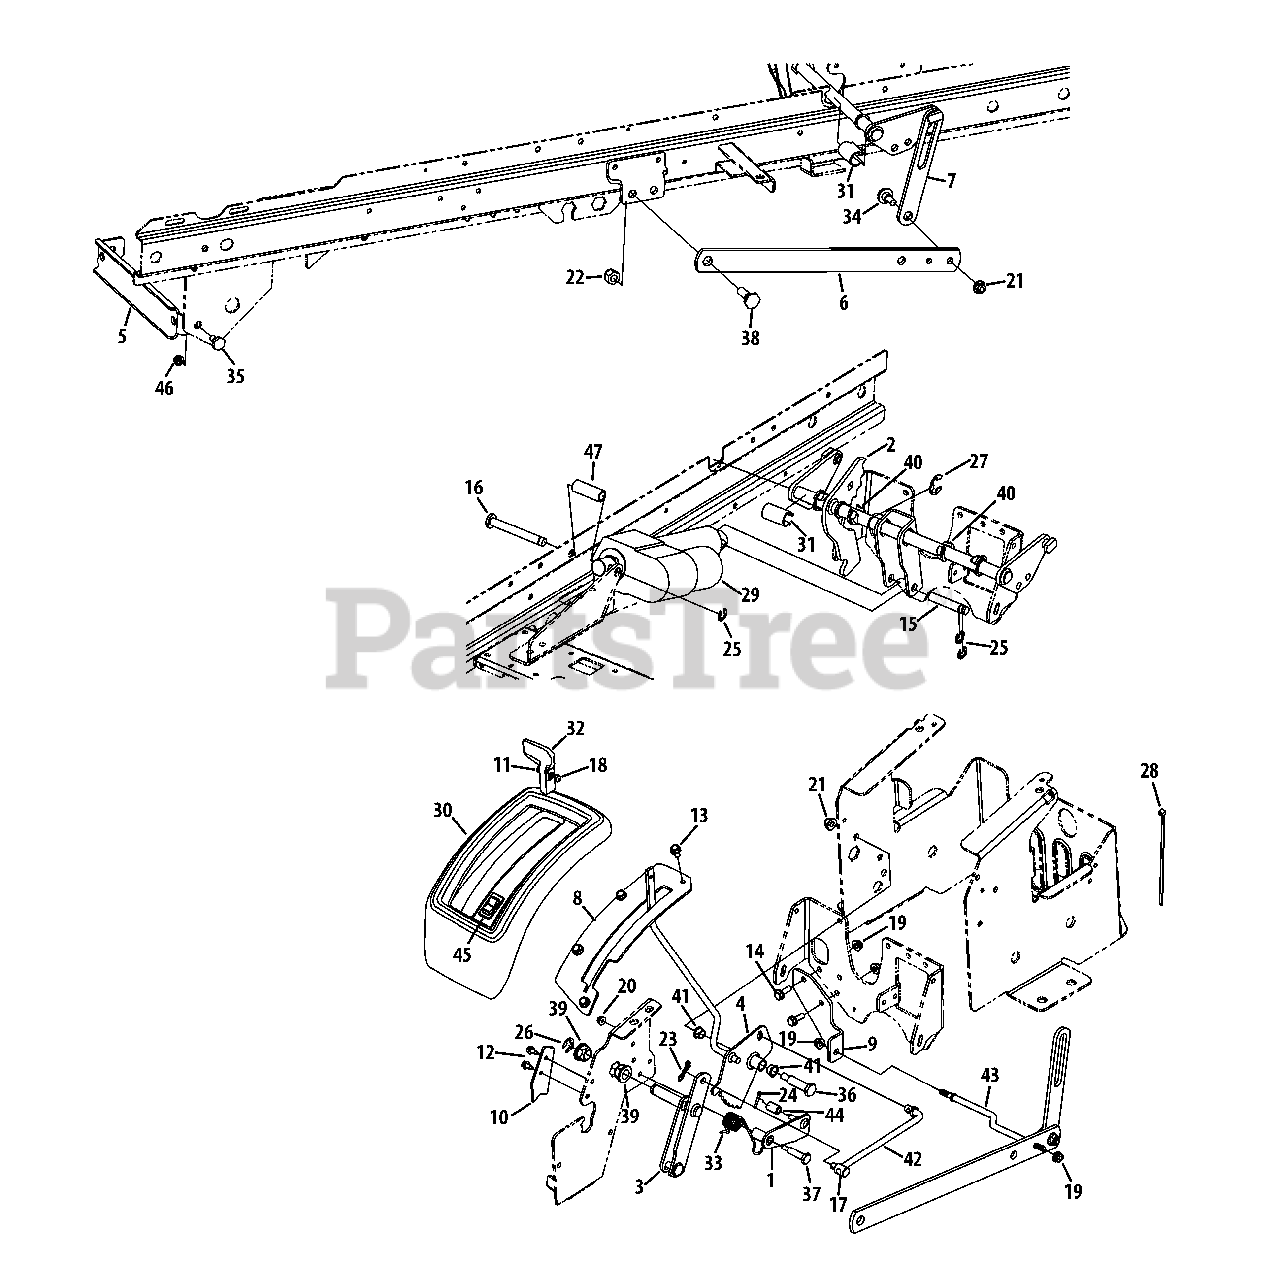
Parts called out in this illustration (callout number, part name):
1	Hub Lift Assembly
2	Electric Shift Assembly
3	Deck Height Adjustment Weldment
4	Lift Lever Bracket Assembly
5	Front Hanger Bracket
7	Lift Link Plate
9	Sway Bar Mount Bracket
10	Bearing Stop Plate
11	Machine Screw, #10-24 x .625
12	Hex Washer Screw, 1/4-20 x .500
13	Hex Washer Screw, 5/16-18 x .625
14	Hex Washer Screw, 5/16-18 x .875
15	PIN, .50 x 3.5
16	Clevis Pin, .50 x 4.0
17	Ferrule, 3/8-24 x .375
18	Hex Lock Nut, #10-24
19	Flange Lock Nut, 5/16-18
20	Flange Lock Nut, 1/4-20
21	Flange Lock Nut, 3/8-16
22	Hex Lock Nut, 1/2-13
23	Bow-Tie Cotter Pin, 72
24	Cotter Pin, .125 x .75
25	E-Ring, .500
26	E-Ring, .625
27	E-Ring, .875
28	Cable Tie, 3/16 x .05 x 7.4
29	Plow Lift Actuator
30	Lift Cover
32	Electric Lift Knob
33	Torsion Spring
34	Shoulder Screw, 3/8-16 x .562 x .360
35	Shoulder Screw, 1/2 x .29
36	Shoulder Screw, .498 x 1.635
37	Shoulder Screw, .374 x 1.375
38	Shoulder Screw, 1/2-13 x .625 x .36
39	Hex Flange Bearing
40	Hex Flange Bearing, .78
41	Flange Bearing, .500 x .34
42	Electric Lift Rod Adjuster
43	Anti-Sway Deck Rod
44	Spacer, .35 x .5 x .851
45	Plow Lift Switch
46	Jam Lock Nut, 3/8-16
47	Spacer, .55 ID x .75 OD x 2.06
